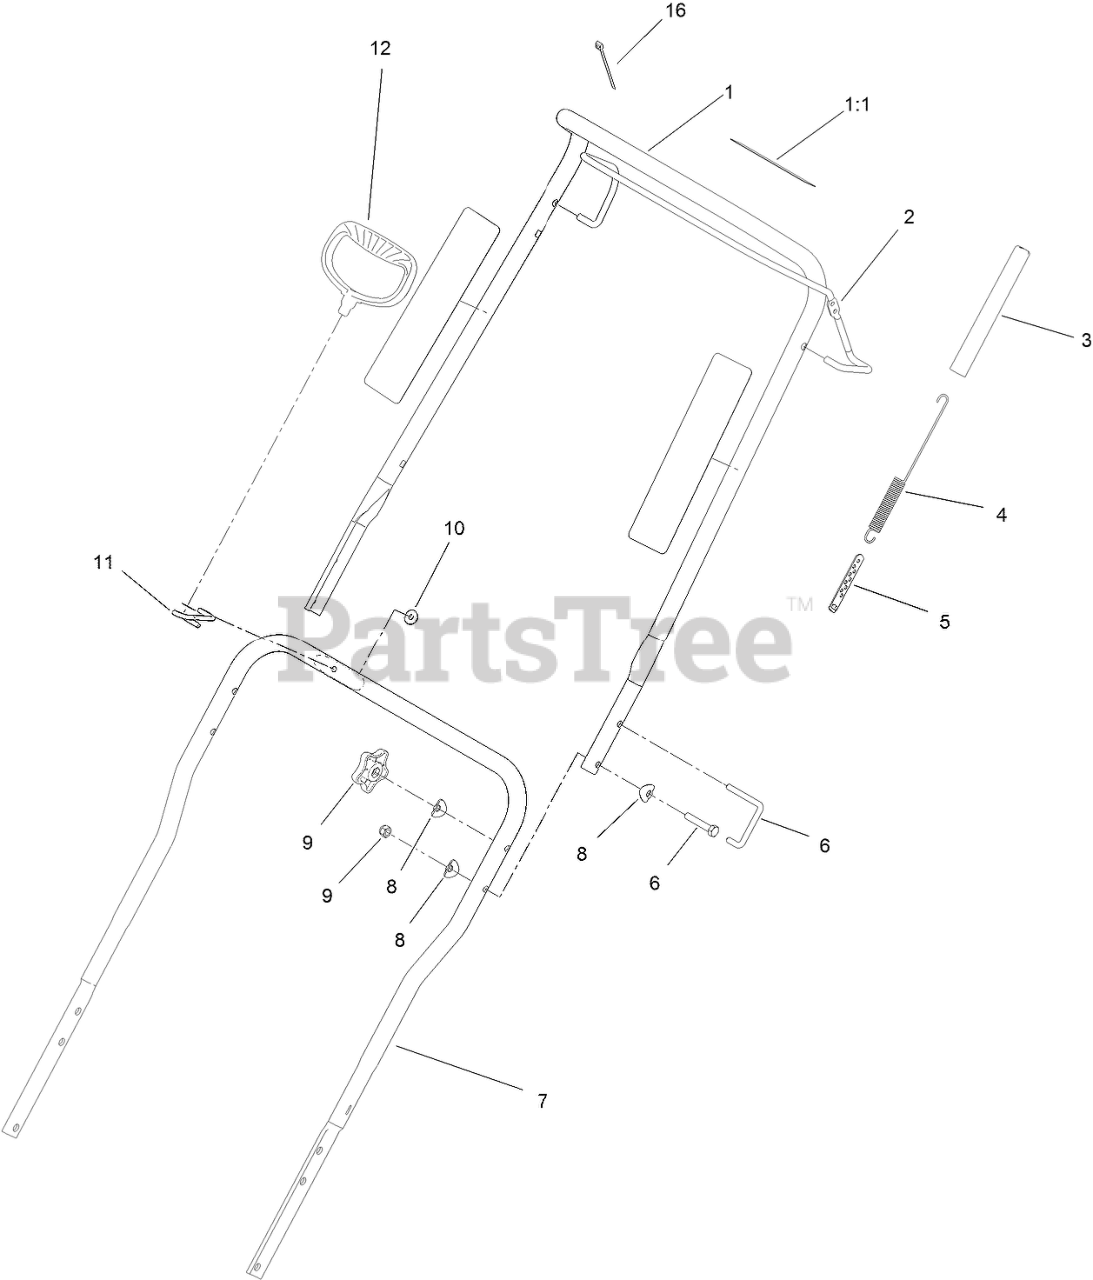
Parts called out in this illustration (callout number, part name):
1	UPPER HANDLE ASM
1:1	DECAL-DRIVE, ROTOR
2	BAIL-CLUTCH
3	COVER-SPRING
4	SPRING-EXTENSION, CLUTCH
5	ADJUSTER-CABLE, CLUTCH
6	LOCK-HANDLE
7	HANDLE-LOWER
8	WASHER
9	KNOB-HANDLE
10	NUT-HF
11	GUIDE-ROPE
12	HANDLE-RECOIL
16	TIE-CABLE
